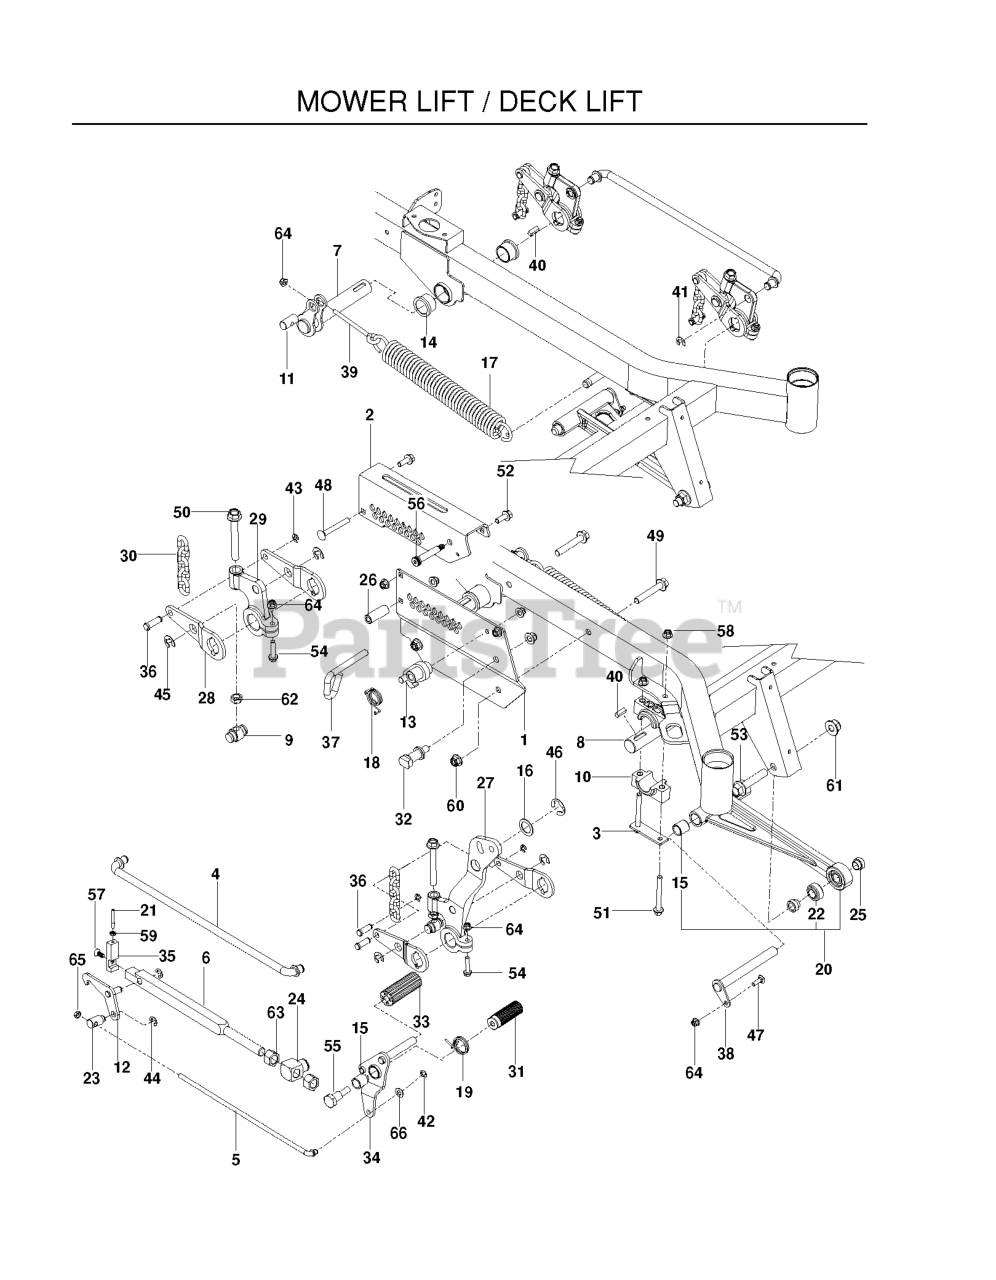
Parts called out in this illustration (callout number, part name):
1	PLATE, INNER HEIGHT, ORANGE
2	PLATE, OUTER HEIGHT ORG
3	PLATE, PILLOW BLACK
4	ROD, LIFT
5	ROD, HEIGHT LATCH
6	BAR, HEIGHT
7	SHAFT, RR LIFT
8	SHAFT, LIFT, FT
9	SHAFT, LIFT TRUNION WSL
10	BLOCK, PILLOW
11	PIVOT, SPRING
12	LATCH, HEIGHT WLDMT
13	LATCH, TRANSPORT WLDMT
14	BUSHING, FLANGE 1.25 X 1.0
15	BUSHING, SLEEVE 3/4 X 1.0
16	MACHINE BUSHING
17	SPRING, EXTENSION
18	SPRING, TORSION
19	SPRING, TORSION
20	ASSEMBLY, STRUT
21	LINK, INDICATOR
22	BALL JOINT, 3/4" SWIVEL
23	SWIVEL, HEIGHT LATCH
24	SWIVEL, HEIGHT BAR
25	SPACER, STRUT
26	SPACER, HEIGHT PLATE
27	ARM, LIFT LEVER
28	ARM LIFT BLK
29	ARM, CAST LIFT
30	LIFT CHAIN
31	PAD, FOOT PEDAL
32	GUIDE, HEIGHT BAR
33	PEDAL, DECK HEIGHT
34	PEDAL, RELEASE WLDMT
35	CAP, HEIGHT BAR
36	PIN, 7/16 CLEVIS
37	PIN, HEIGHT
38	PIN, STRUT
39	EYE BOLT 4.5`
40	KEY, 5/16 SQ X 1.0
41	E-RING 5/8
42	E RING 3/8"
43	RING, E, 7/16
44	E-RING 1/2 (2 2)
45	E RING 3/4
46	E-RING 1"
47	RHSNB 5/16C X 1
48	3/8-16 X 3` CARR BOLT
49	HFFS 1/2-13 X 3 GD 5 ZD
50	HHFS 1/2-13 X 4 GR 5
51	HHFS 3/8-16 X 3.5 GD 5 ZD
52	HHFS 3/8-16 X 1 GRD 5 ZD
53	HHFS 5/8-11 X 3.0 GD 8 ZD
54	HHFS 5/16-18 X 1.5 GD 5
55	BOLT, SHOULDER
56	BOLT, SHOULDER, 1/2 X 2.25
57	SCREW, 5/16-18 X 3/4 FLAT HEX
58	NUT 3/8-16 HEX FLG NYLOC ZD
59	NUT 1/4-20 JAM
60	NUT, 1/2-13 HEX FLG NYLOC ZD
61	NUT 5/8-11 FLG NYLOC ZD
62	NUT 1/2 HEX JAM
63	NUT 3/4-10 HEX ZD
64	5/16-18 NYLOC FLANGE NUT
65	NUT 3/8-24 JAM
66	WASHER 3/8 SAE FLAT
